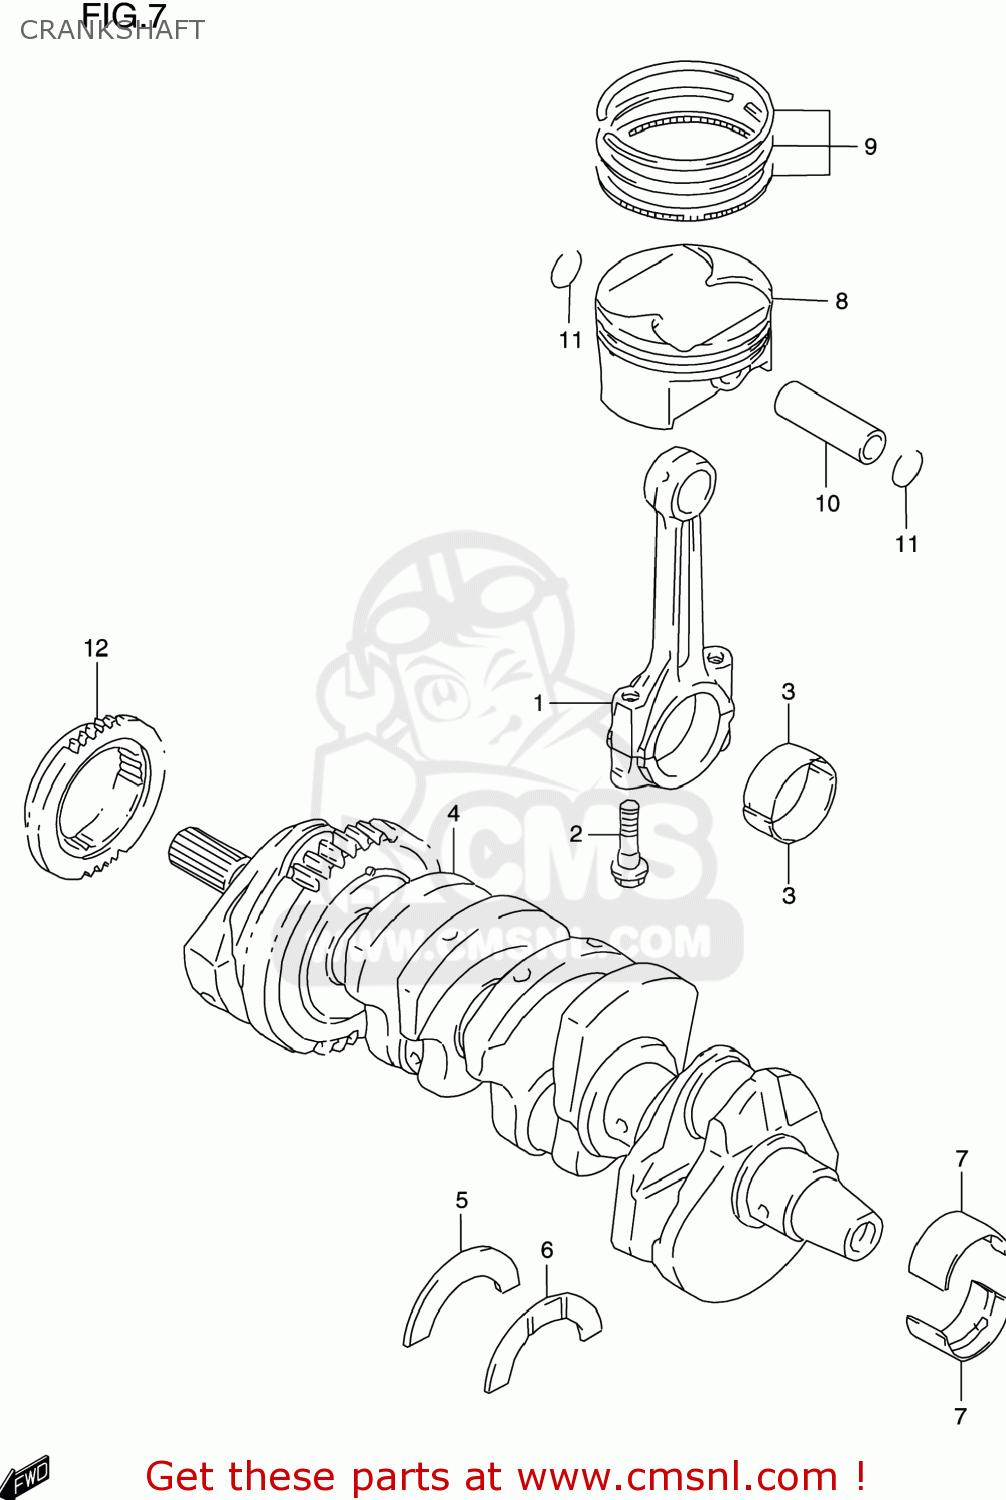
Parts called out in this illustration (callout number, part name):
1	CONNECTING ROD ASSEMBLY
2	BOLT,CONNECTING ROD
3	BEARING,CRANK PIN
4	CRANKSHAFT SET
5	BEARING,CRANK THRUST(GREEN)
6	BEARING,CRANK THRUST(RED)
7	BEARING,CRANKSHAFT
8	PISTON
9	RING SET,PISTON
10	PIN,PISTON
11	CIRCLIP
12	SPROCKET,CAM CHAIN DRIVE
